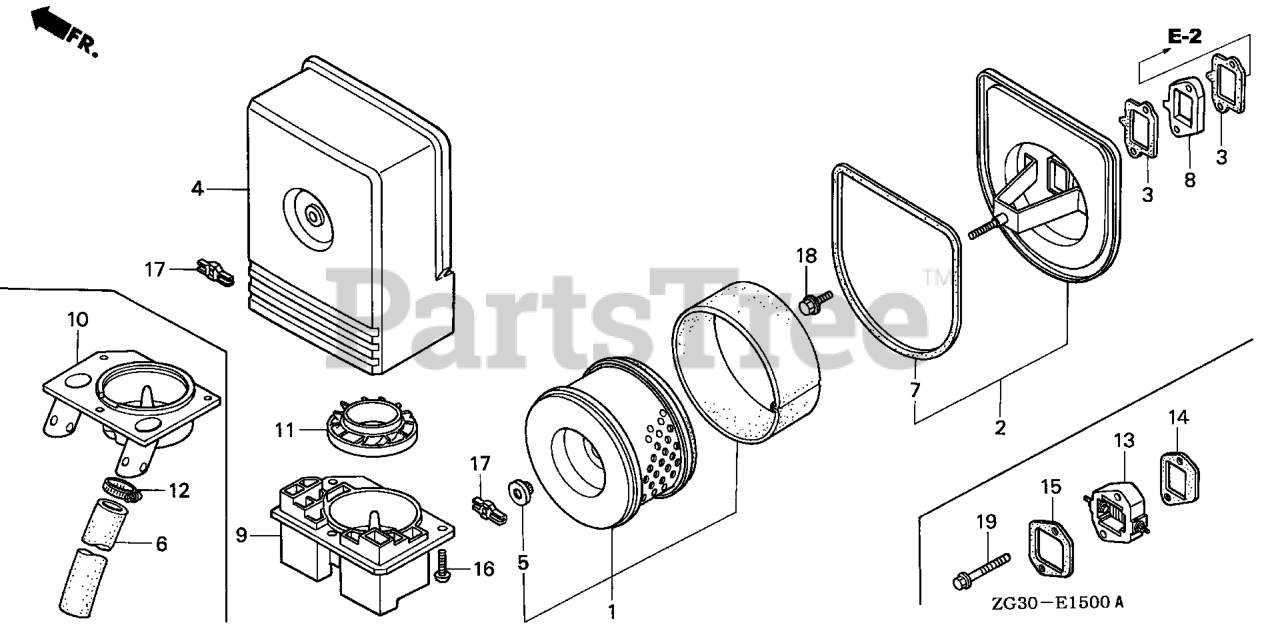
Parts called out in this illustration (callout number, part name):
1	ELEMENT, AIR CLEANER (WET)
2	HOUSING, AIR CLEANER
3	GASKET, AIR CLEANER
4	COVER, AIR CLEANER
5	GROMMET, AIR CLEANER
7	GASKET, AIR CLEANER HOUSING
9	CASE, PRE CLEANER
11	GUIDE, PRE AIR CLEANER
16	SCREW, PAN (5X16.5)
17	WINGNUT, AIR CLEANER COVER
18	BOLT, FLANGE (8X22) Use from Engine SN 1609607.
